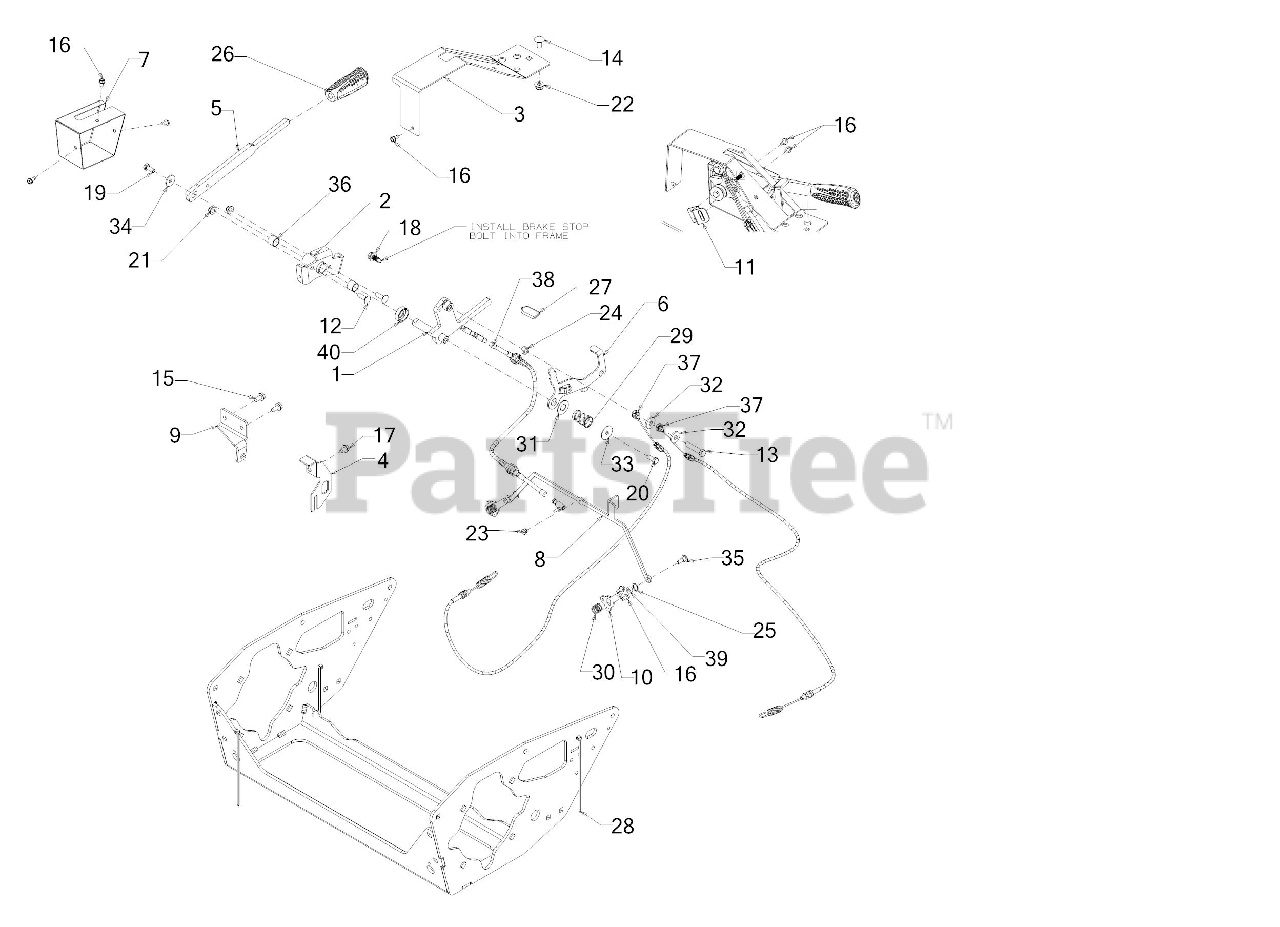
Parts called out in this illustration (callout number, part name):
1	PIVOT BRAKE SHAFT ASSEMBLY
2	PIVOT TUBE ASSEMBLY
4	NEUTRAL SWITCH MOUNTING BRACKET
5	PARKING BRAKE LEVER
6	DUMP VALVE RELEASE LEVER
7	BRAKE LEVER PIVOT COVER
8	DUMP VALVE ACTUATOR BRACKET
9	CABLE MOUNTING BRACKET
10	BYPASS LEVER
11	3-POLE SWITCH BRACKET
12	CARRIAGE BOLT 5/16-18 x 1.00
13	HEX SCREW 3/8-16 x 1.75 GR5
14	CARRIAGE BOLT 3/8-16 x .750 GR5
15	SCREW 5/16-18 x .750
16	SCREW 1/4-20 X.500
17	SCREW 5/16-18 x .500
18	HEX SCREW WASH TT 3/8-16 x .875
19	SCREW 5/16-18 x .750
20	SCREW 5/16-18 x .75 GR5
21	FLANGE LOCK NUT 5/16-18
24	HEX NUT
25	SNAP RING
27	SEAT ADJUSTER GRIP
28	7" CABLE TIE
29	COMPRESSION SPRING .844X.970X1.50
30	COMPRESSION SPRING
31	FLAT WASHER .640ID X1.24OD x .06
32	FLAT WASHER .385 x 1.00 x .135
33	FLAT WASHER .322 ID x 1.25 x .060
34	FLAT WASHER 1.0 OD:.331 ID
35	SHOULDER SCREW .375X.280:1/4-14
36	SLEEVE BEARING
37	BRAKE CABLE
38	NEUTRAL CONTROL CABLE
